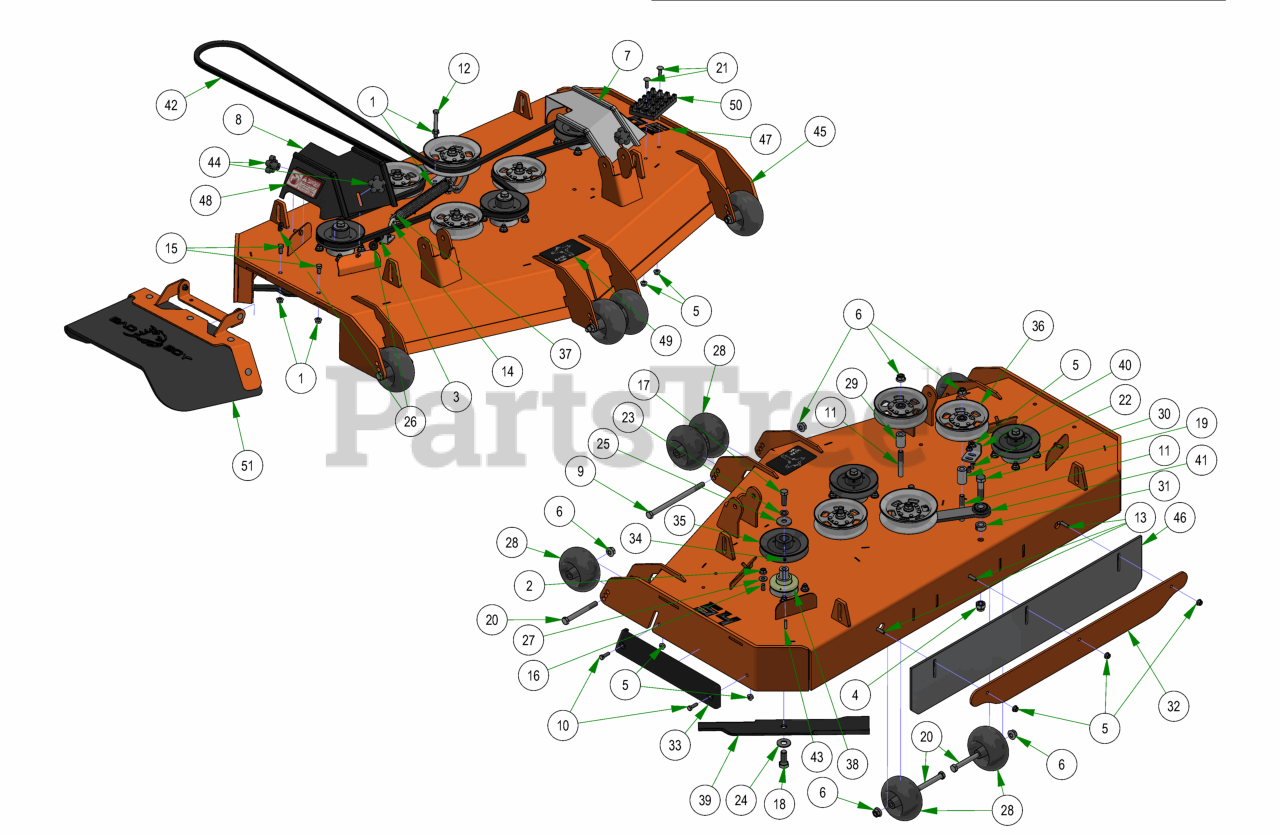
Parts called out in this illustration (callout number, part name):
1	3/8-16 HEX SERRATED FLANGE NUT HARD/ZINC
2	3/8-16 NYLON INSERT FLANGE LOCKNUT (GR.F) ZINC
3	3/8-16 HEX NUT ZINC
4	5/8-11 NYLON INSERT LOCKNUT ZINC
5	5/16-18 NYLON INSERT FLANGE LOCKNUT ZINC
6	1/2-13 NYLON INSERT FLANGE LOCKNUT ZINC
7	2019 54" Left Outlaw Gen2 Pulley Cover
8	2019 54" Right Outlaw Gen2 Pulley Cover
9	1/2-13 X 8 HEX CAP SCREW GR 5 ZINC
10	5/16-18 X 1 HEX CAP SCREW (GR.5) ZINC
11	1/2-13 X 3-1/2 HEX FLANGE BOLT (GR.8) ZINC
12	3/8-16 X 3 HEX CAP SCREW (GR.5) ZINC
13	5/16-18 X 1-1/4 CARRIAGE BOLT ZINC
14	4" 3/8-16 Eye Bolt
15	3/8-16 X 3/4 HEX CAP SCREW (GR.5) ZINC
16	3/8-16 X 1-1/2 HEX CAP SCREW (GR.5) ZINC
17	1/2-20 X 1-1/2 HEX CAP SCREW (GR.5) ZINC
18	5/8-18 X 1-1/2 HEX CAP SCREW (GR.8) ZINC YELLOW
19	5/8-11 X 2-1/2 HEX CAP SCREW (GR.5) ZINC
20	1/2-13 X 4-1/2 HEX CAP SCREW (GR.5) ZINC
21	5/16-18 X 1 CARRIAGE BOLT (GR.8) ZINC
22	5/16-18 X 7/8 CARRIAGE BOLT ZINC
23	1/2 SPLIT LOCKWASHER (GR.8) ZINC/YELLOW
24	5/8 USS FLAT WASHER (1-3/4" OD) GR.8 ZINC YELLOW
25	1/2 BELLEVILLE WASHER (1-5/8 OD X .140 THK) ZINC
26	.360 ID X .983 OD X .120 THICK FLAT WASHER NYLON BLACK
27	5/16 USS FLAT WASHER (7/8 OD) ZINC
28	2019 Deck Wheel
29	.502 ID X .750 OD X 1.500 Long Spacer
30	1 3/4" Pulley Spacer
31	5/8 SOLID SHAFT COLLAR (W/1 SET SCREW) ZINC
32	61 Bolt in Baffle Deck v2 Stripping Plate
33	REVISED TRIM BUMPER_20180226
34	5/16-24 X 1/4 SOCKET SET SCREW (CUP PT) PLAIN
35	5.25" Deck Spindle Pulley
36	5-3/4 Idler Pulley
37	2019 Outlaw Gen2 Deck Spring
38	OUTLAW SPINDLE ASSEMBLY
39	54" Fusion Blade for ZT/Mav/Outlaw/Revolt
40	2019 Deck Eye Bolt Tab
41	2019 Rebel Rogue Deck Idler
42	B165 Belt-60 54" deck Outlaw
43	1/4 X 1 SQ MACHINERY KEY 1018 STL PLN
44	5/16" Knob
45	2019 Sloped 54" Deck
46	R Series Rubber For Deck
47	54" Deck Decal
48	Danger Decal-Spindle/Discharge
49	2019 Rebel & Rogue Deck Belt Route Decal
50	Deck Step Assembly
51	2019 Outlaw Gen2 Chute Assembly
